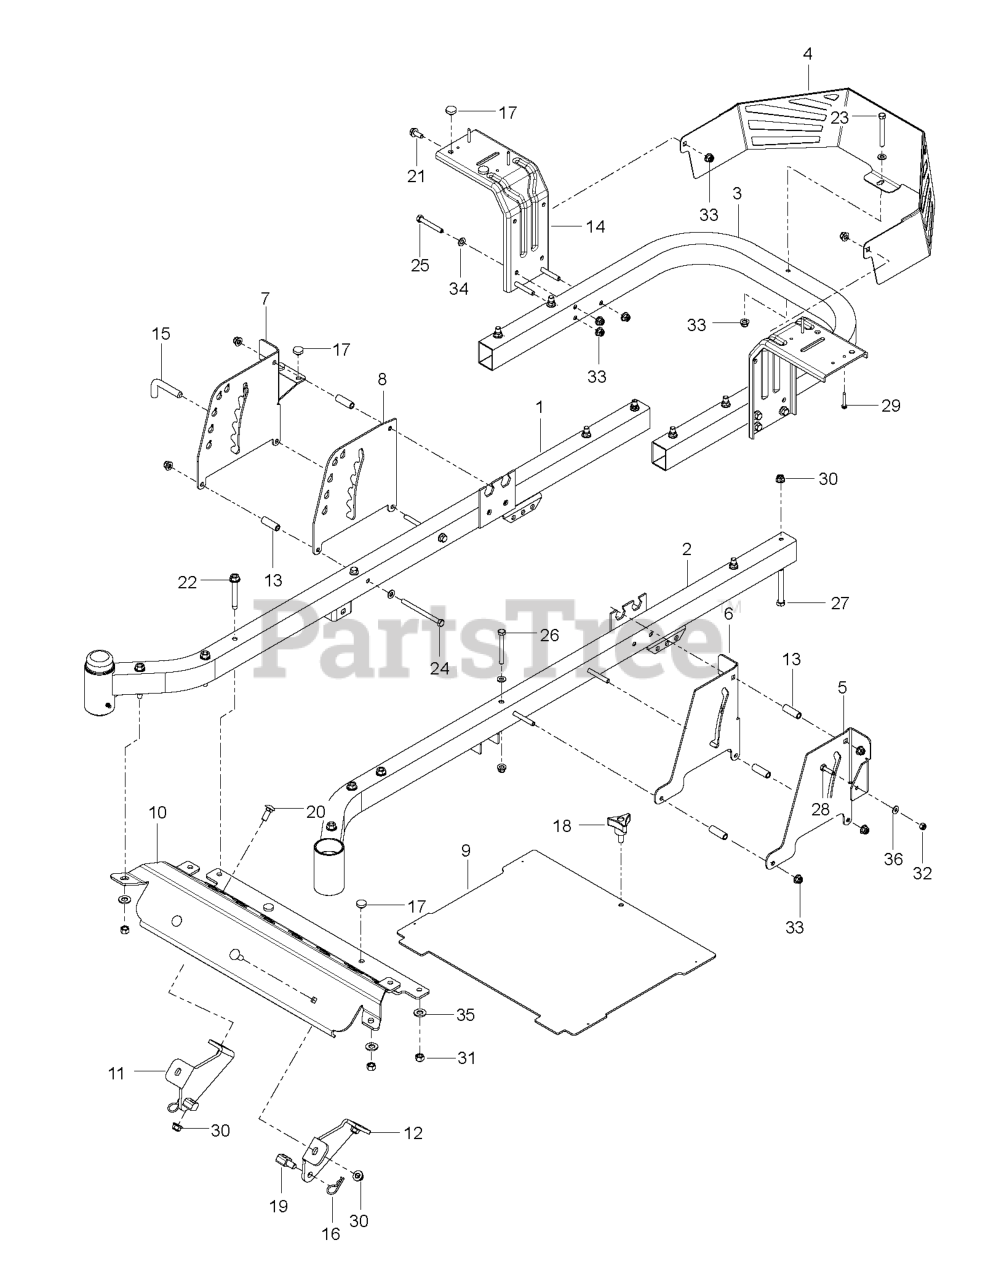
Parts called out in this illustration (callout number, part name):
1	FRAME TUBE RZ MAIN WELDMENT RI
2	FRAME TUBE RZ MAIN WELDMENT LE
3	FRAME REAR TUBE SNAPPER RED X6
4	GUARD HEAT SHIELD,RZ,21IN FRAM
5	PLATE, OUTER BRAKE, BLACK
6	PLATE, BRAKE LATCH, BLACK
7	PLATE.DECK HEIGHT.PNT.431.RZ
8	PLATE, DECK HEIGHT, BLACK
9	KIT.PLATE.FLOOR.W/DCL.REDM.672
10	FOOT REST, MED BLK
11	MOUNT.STRUT.RH.431
12	MOUNT.STRUT.LH.431
13	SPACER.334.ID.5.OD.1.5.L
14	FENDER.SUPPORT.PNT.X431
15	PIN.DECK.HEIGHT.RZ
16	HAIRPIN #4
17	GROMMET, BUMPER
18	KNOB W/STUD
19	SWIVEL.TRUNION.LINK.DECK.FRONT
20	RHSNB 3/8C X 1
21	HHFS 5/16-18 X 3/4
22	HHFS 3/8-16 X 3 GRD 5 ZD
23	BOLT HEX FLGHD 5/16-18X3 GR. 5
24	HCS 5/16C X 4
25	BOLT.FIN HEX 5/16-18UNC X2 1/4
26	BOLT HEX
27	BOLT.HEX.FIN.3/8-16 X 3.GR5
29	SCR #10-12X1-1/2HEX WASH HD ZD
30	NUT 3/8-16 HEX FLG NYLOC ZD
31	NUT HEX 3/8-16 NYLON, THIN
32	RP_NUT 1/4-20 NYLOC
33	5/16-18 NYLOC FLANGE NUT
34	WASHER
35	WASHER 3/8 FLAT
36	WASHER
